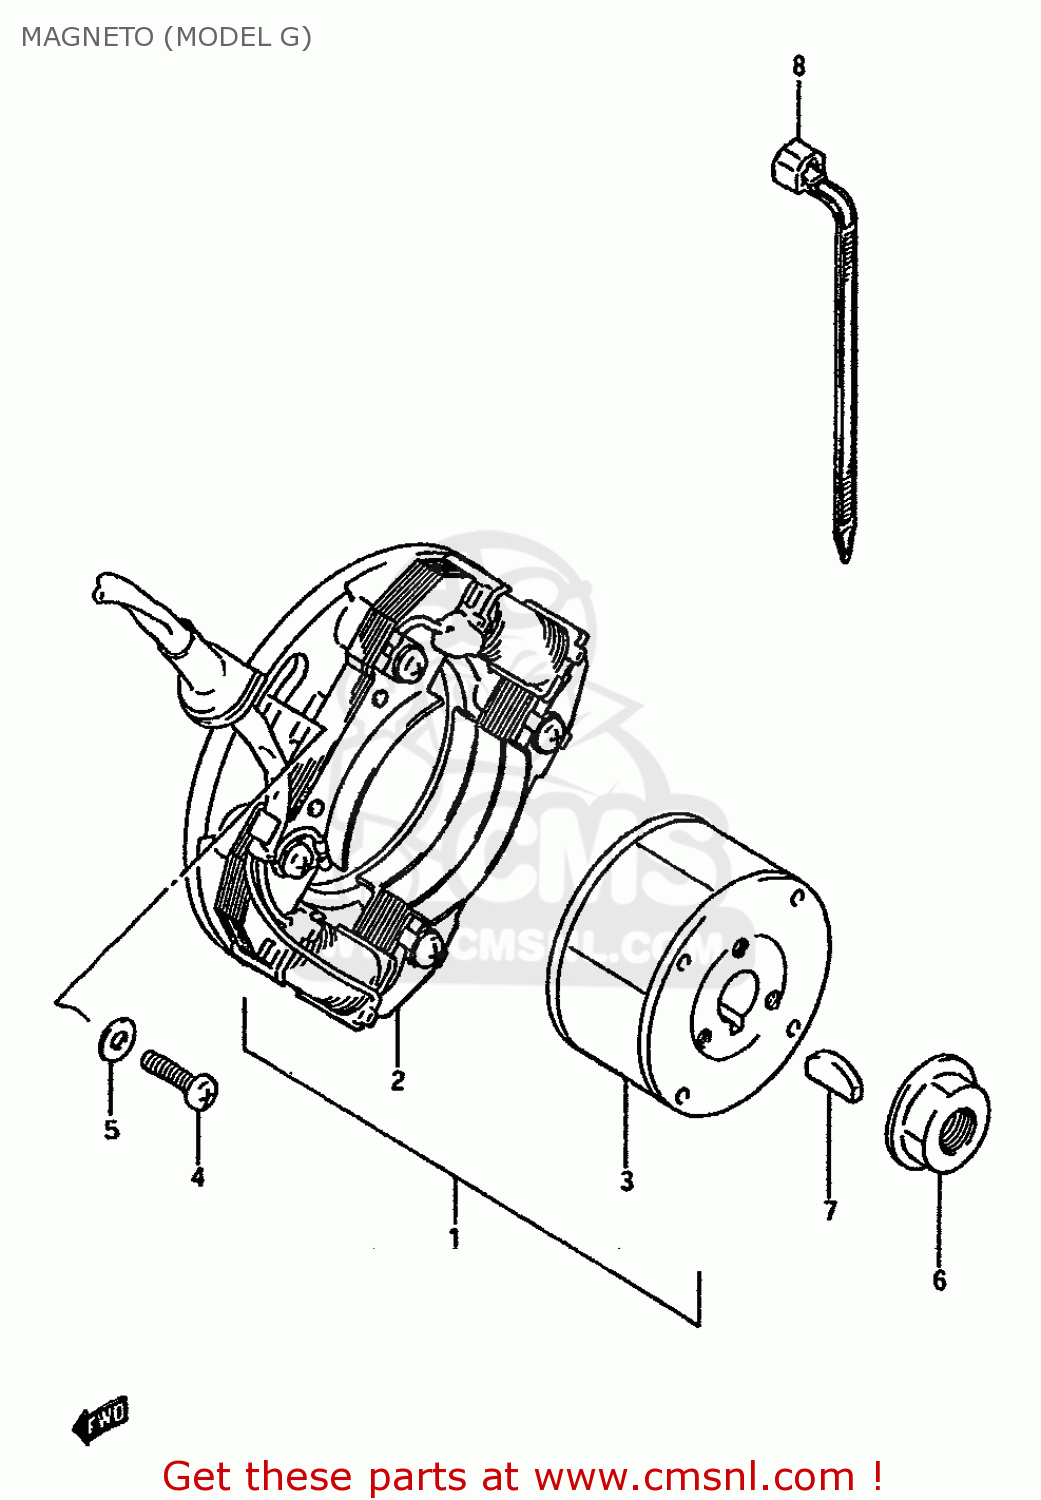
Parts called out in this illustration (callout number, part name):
1	MAGNETO ASSEMBLY
2	STARTER ASSY
3	ROTOR
4	SCREW
5	WASHER
6	NUT
7	KEY 4MM
8	CLAMP(L:125)
